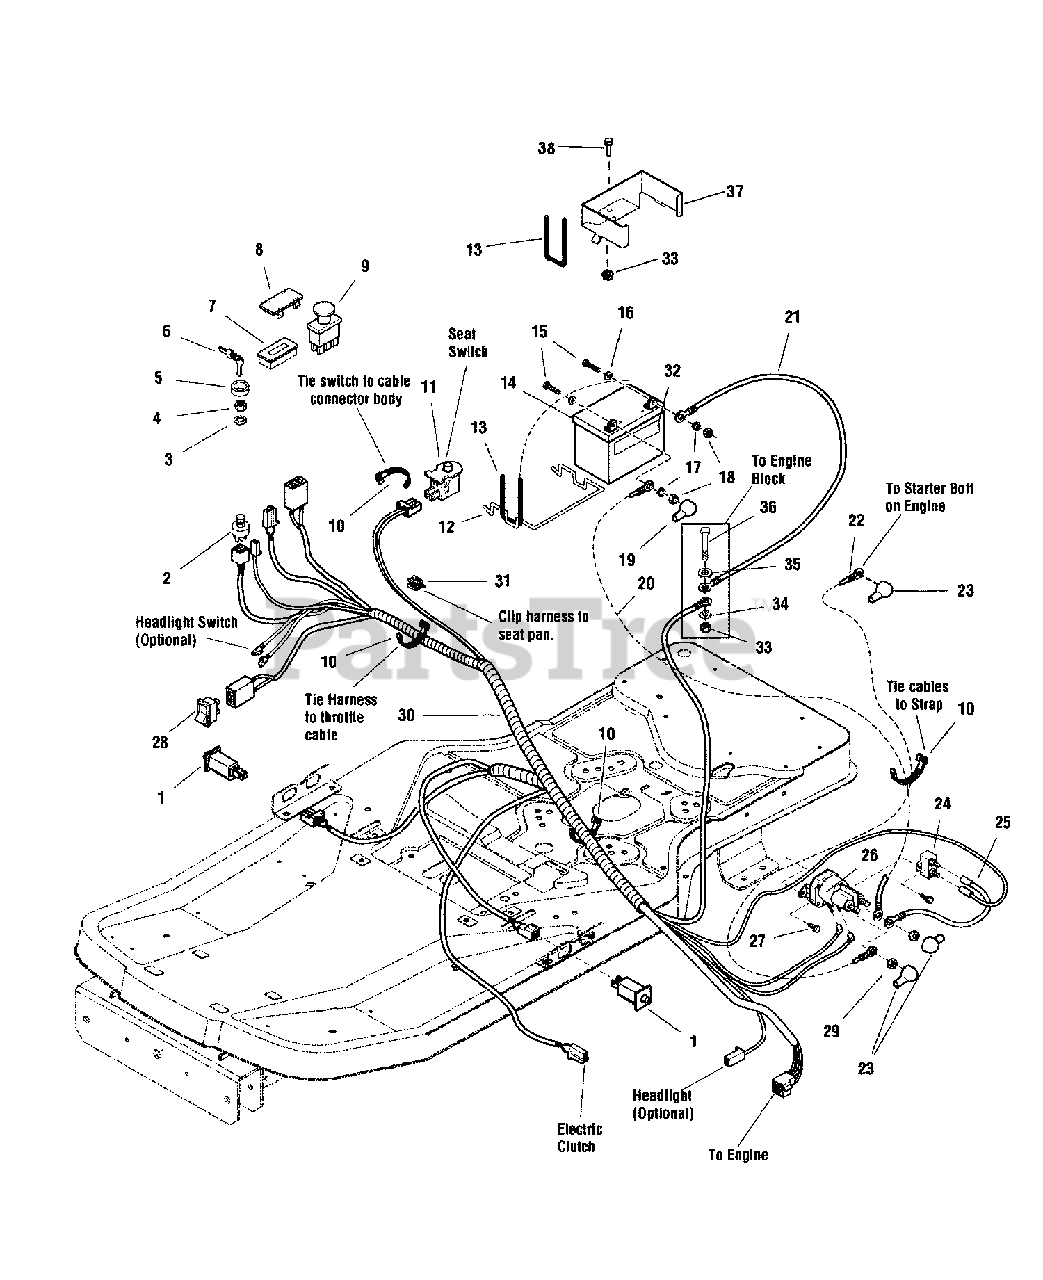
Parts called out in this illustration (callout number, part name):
1	SWITCH, Push Button (NO/NC) Snap-In
2	SWITCH ASSEMBLY, Ignition
3	LOCKWASHER, Internal Tooth 5/8" Thin
4	NUT, 5/8-32 Hex Flange (Ignition Switch Die Cast)
5	COVER, Ignition Switch
6	KEYS (set of two)
7	HOUR METER, No Alarms
8	PLUG, Hole (Black Plastic)
9	SWITCH, PTO, Push/Pull Symbols
10	TIE, Self Locking, .184 Wide 7.31 Long
11	SWITCH, Push Button (NC)
12	BRACE, Battery, .19 Dia. Wire
13	STRAP, Black Rubber, .19 Square 7.88 O.D. Battery
14	BATTERY, 12 Volt, 230 CCA
15	SCREW, 1/4-20 x 3/4" Hex Head Cap, GR5
16	WASHER, 1/4, .27 I.D. x .62 O.D. x .05 Thick
17	WASHER, 1/4" Spring Lock
18	NUT, 1/4-20 Hex
19	BOOT, Insulator, Red PVC Warning
20	CABLE, #6 x 10 Long, Red Two-Ring Terminals
21	CABLE, # 6 x 26 Long Two-Ring Terminals
22	CABLE, #6 x 15 Long, Two-Ring Terminals
23	COVER, Terminal Red PVC
24	BREAKER, Circuit 12 Volt 20 AMP
25	WIRE, 12 Gage
26	SOLENOID, Super Trombetta - 2 Terminal
27	SCREW, 1/4-20 x 1/2" Hex Washer Head Screw Black (Taptite)
28	SWITCH, Electric Height-of-Cut
29	NUT, 5/16-24 Hex Keps
30	HARNESS, Wiring
31	CLIP, Cable, .390 Wire Dia.
32	DECAL, Danger Poison
33	NUT, 5/16-18 Hex Flange Lock, Small - Black
34	WASHER, 3/8" External Tooth Lock
35	WASHER, .312 (.34 I.D. x.75 O.D.)
36	SCREW, 5/16-18 x 2" Hex Head Cap
37	BRACKET, Battery Hold Down
38	BOLT, 5/16-18 x 7/8" Hex Flange Lock
